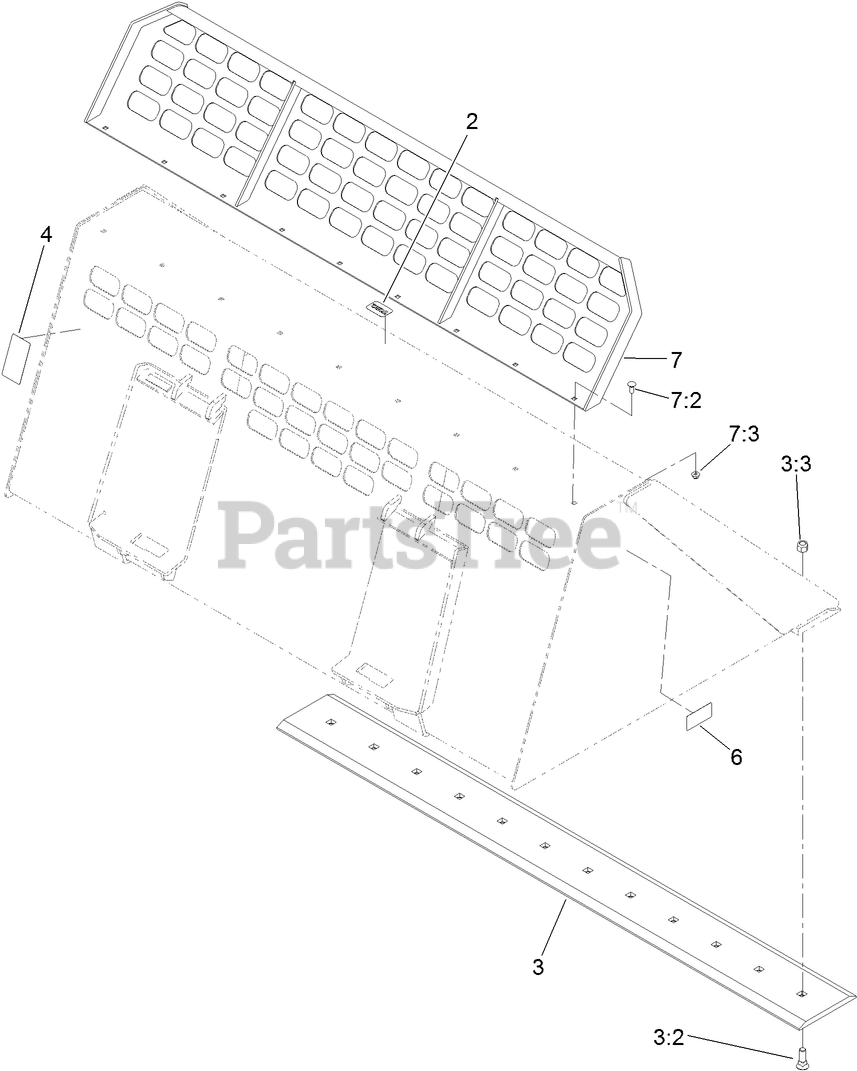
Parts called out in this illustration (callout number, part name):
2	DECAL
3	72IN BOLT-ON EDGE KIT
3:2	BOLT-PLOW
3:3	NUT-LOCK, NI
4	DECAL-WARNING, CAPACITY
6	DECAL-DANGER
7	SPILL GUARD ASM
7:2	SCREW-HH
7:3	NUT-HF, NI
